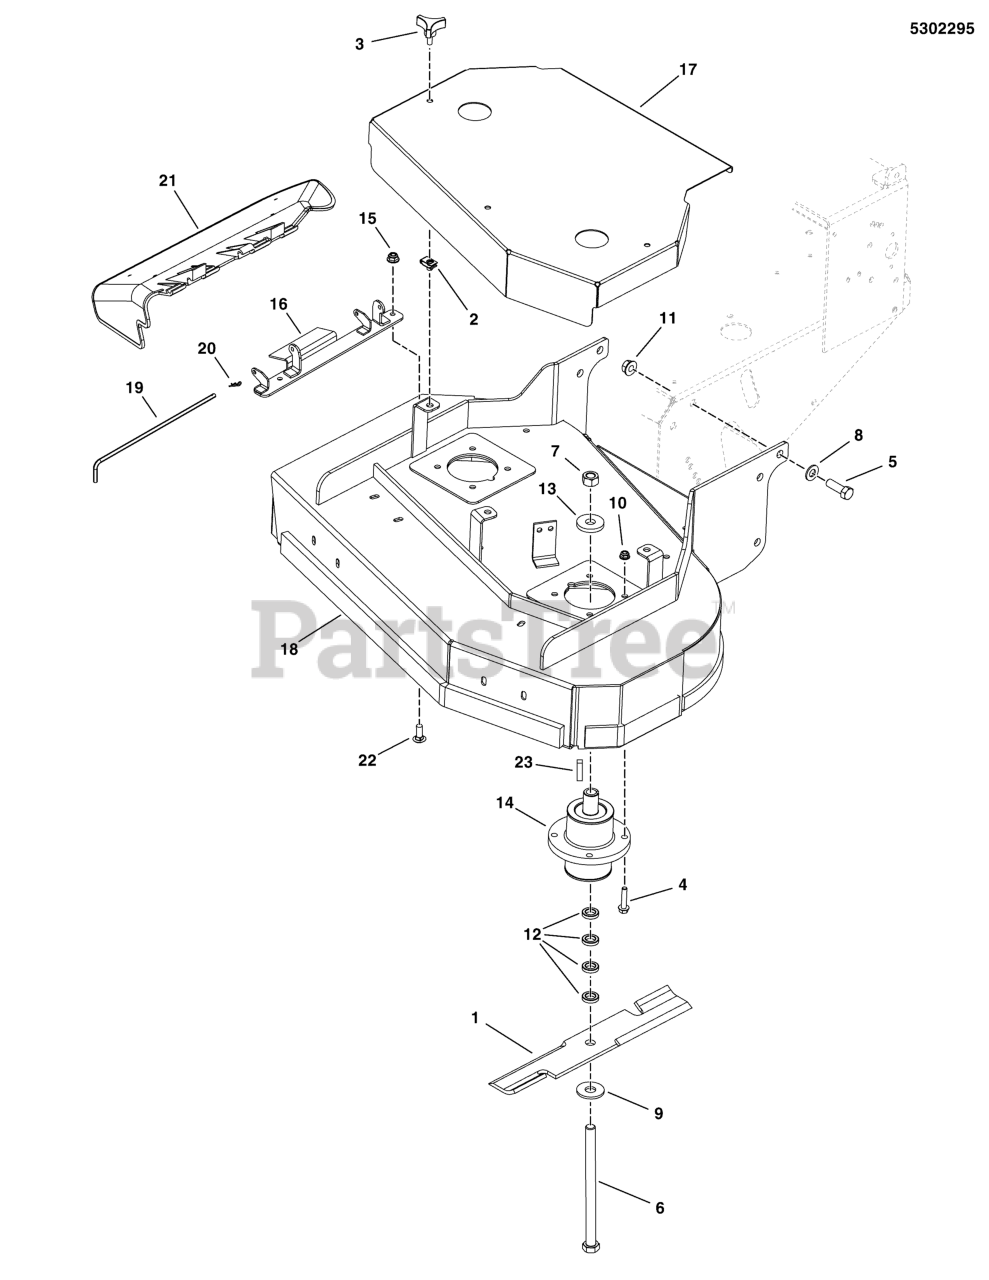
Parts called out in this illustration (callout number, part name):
1	BLADE, 16.25
2	BODY CLIP, 5/16-18-7GA MATERIAL
3	KNOB, 5/16-18 X 1.00, ROSETTE, BLK
4	BOLT, 5/16-18 X 1 1/2 FLANGE
5	BOLT, 1/2-20 X 1-1/2, GD5 CZ
6	BOLT, 5/8-11 X 9 GD5
7	NUT, 5/8-11 HEX
8	WASHER, 1/2 SAE
9	WASHER, BLADE BOLT, 9/16" F436, CZ
10	NUT, 5/16-18 HEX NYLOCK FLANGE
11	NUT, Hex, Nylon Lock, 1/2-20
12	SPACER, .63 X 1.06 X .23
13	SPACER, .64 X 1.75 X .25
14	ASSM, SPINDLE, THRU BORE, BGF
15	NUT, 3/8-16 HEX NYLOCK FLANGE
16	WELD, DISCHARGE CHUTE MOUNT - RED
17	GUARD, DECK 32 - RED
18	DECK SHELL W/ DECALS, SW5 32"
19	ROD, QUICK CONNECT
20	PIN, HAIR, .0915 X 1-7/8
21	DEFLECTOR-BLACK PLASTIC 30">50" DECKS
22	BOLT, RD HD SH SQ NK 3/8- 16X1.000 G5 BL
23	KEY, 1/4 SQ X 1-1/4
